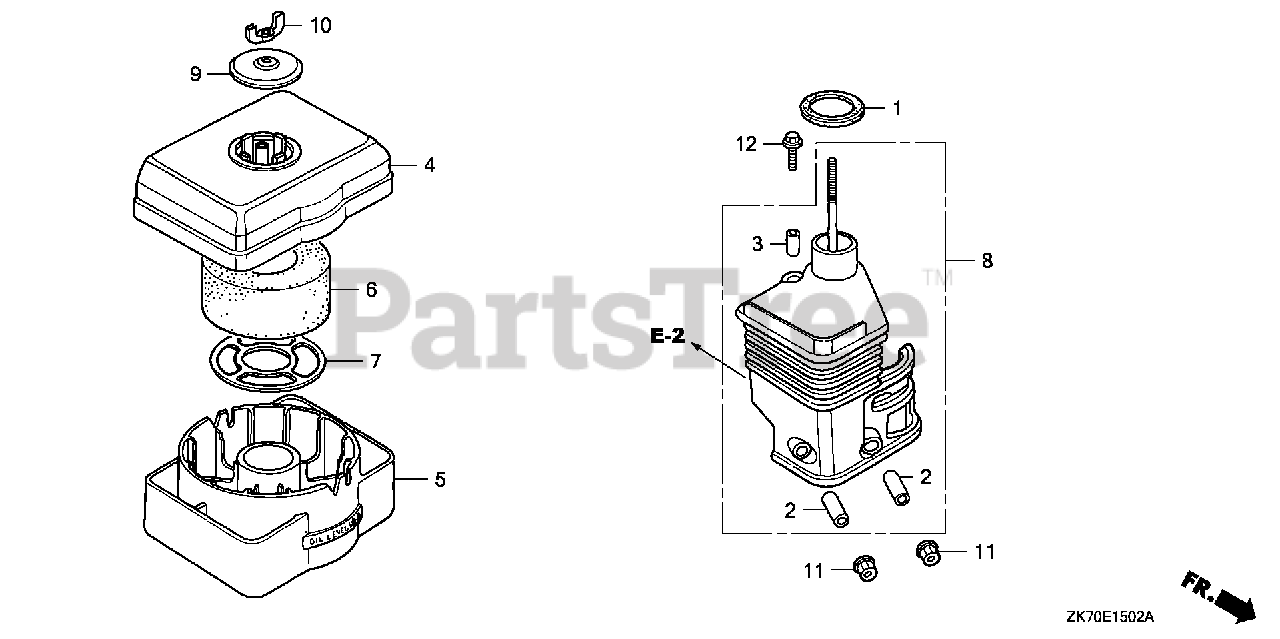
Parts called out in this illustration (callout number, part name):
1	GASKET, ELBOW
2	COLLAR, AIR CLEANER
3	COLLAR B, AIR CLEANER
4	BODY, CLEANER (OIL BATH)
5	PAN, CLEANER OIL (OIL BATH)
6	ELEMENT, AIR CLEANER (OIL BATH)
7	GRID, AIR CLEANER
8	ELBOW, AIR CLEANER
9	CAP, CLEANER
10	NUT, TOOL BOX SETTING
11	NUT, FLANGE (6MM)
12	BOLT, FLANGE (6X20)
